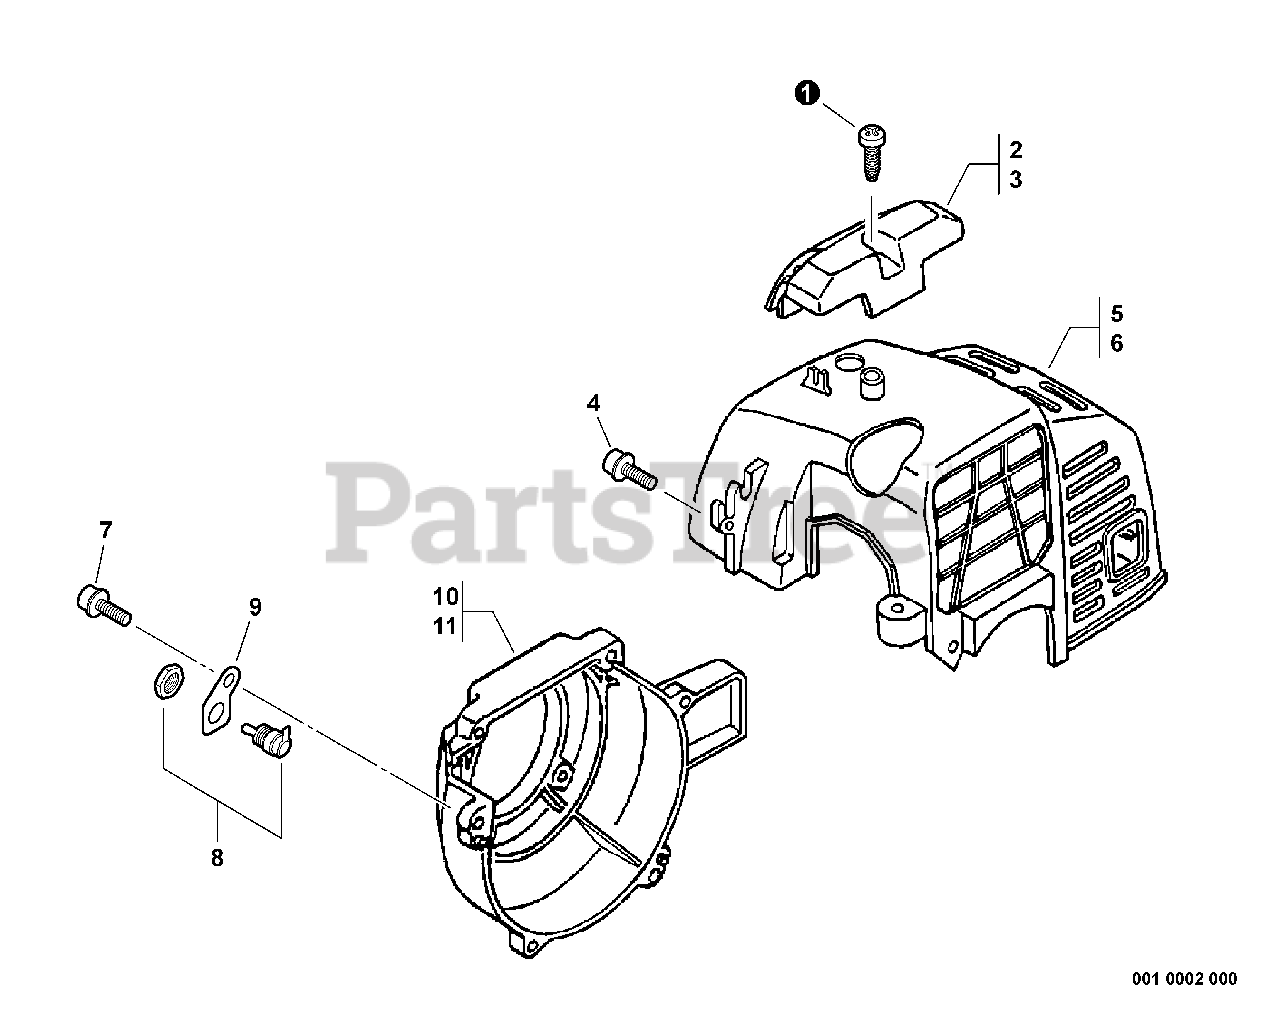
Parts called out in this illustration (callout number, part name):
1	SCREW 5×16
2	GUARD, TOP - GRAY
3	GUARD, TOP - BLACK
4	SCREW 4×12
5	COVER, ENGINE - GRAY
6	COVER, ENGINE - ORANGE
7	BOLT 4×16
8	SWITCH, ON-OFF
9	BRACKET, SWITCH
10	COVER, FAN - GRAY
11	COVER, FAN - ORANGE
